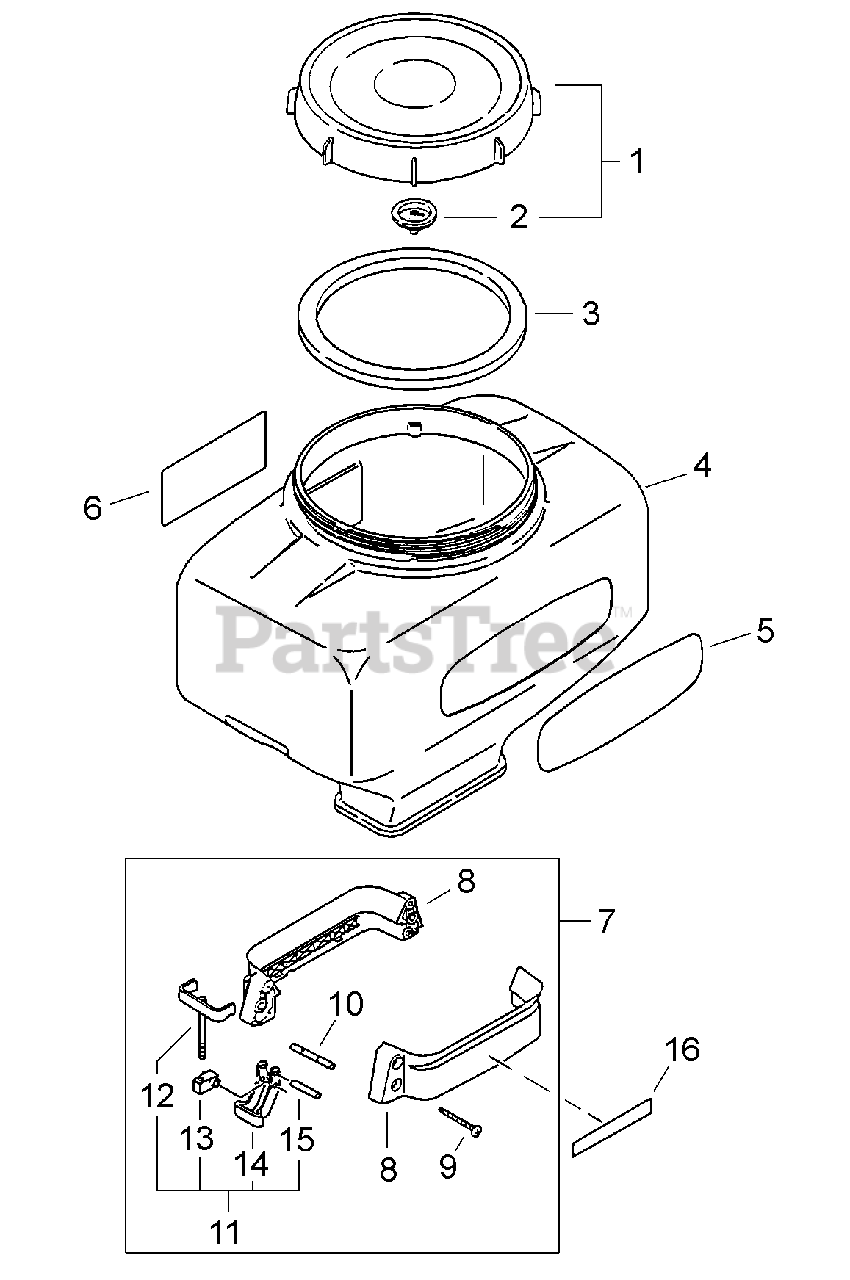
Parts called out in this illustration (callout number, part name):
1	CAP, CHEMICAL TANK
2	VENT, TANK
3	GASKET, CAP
4	TANK, CHEMICAL - 23 LITER
5	LABEL - ECHO
6	LABEL - CAUTION
7	BRACKET ASSY
9	SCREW - 5X35
11	CLAMP ASSY
13	CONNECTOR
14	BRACKET, TANK
15	PIN
16	LABEL - MODEL DM-6110
